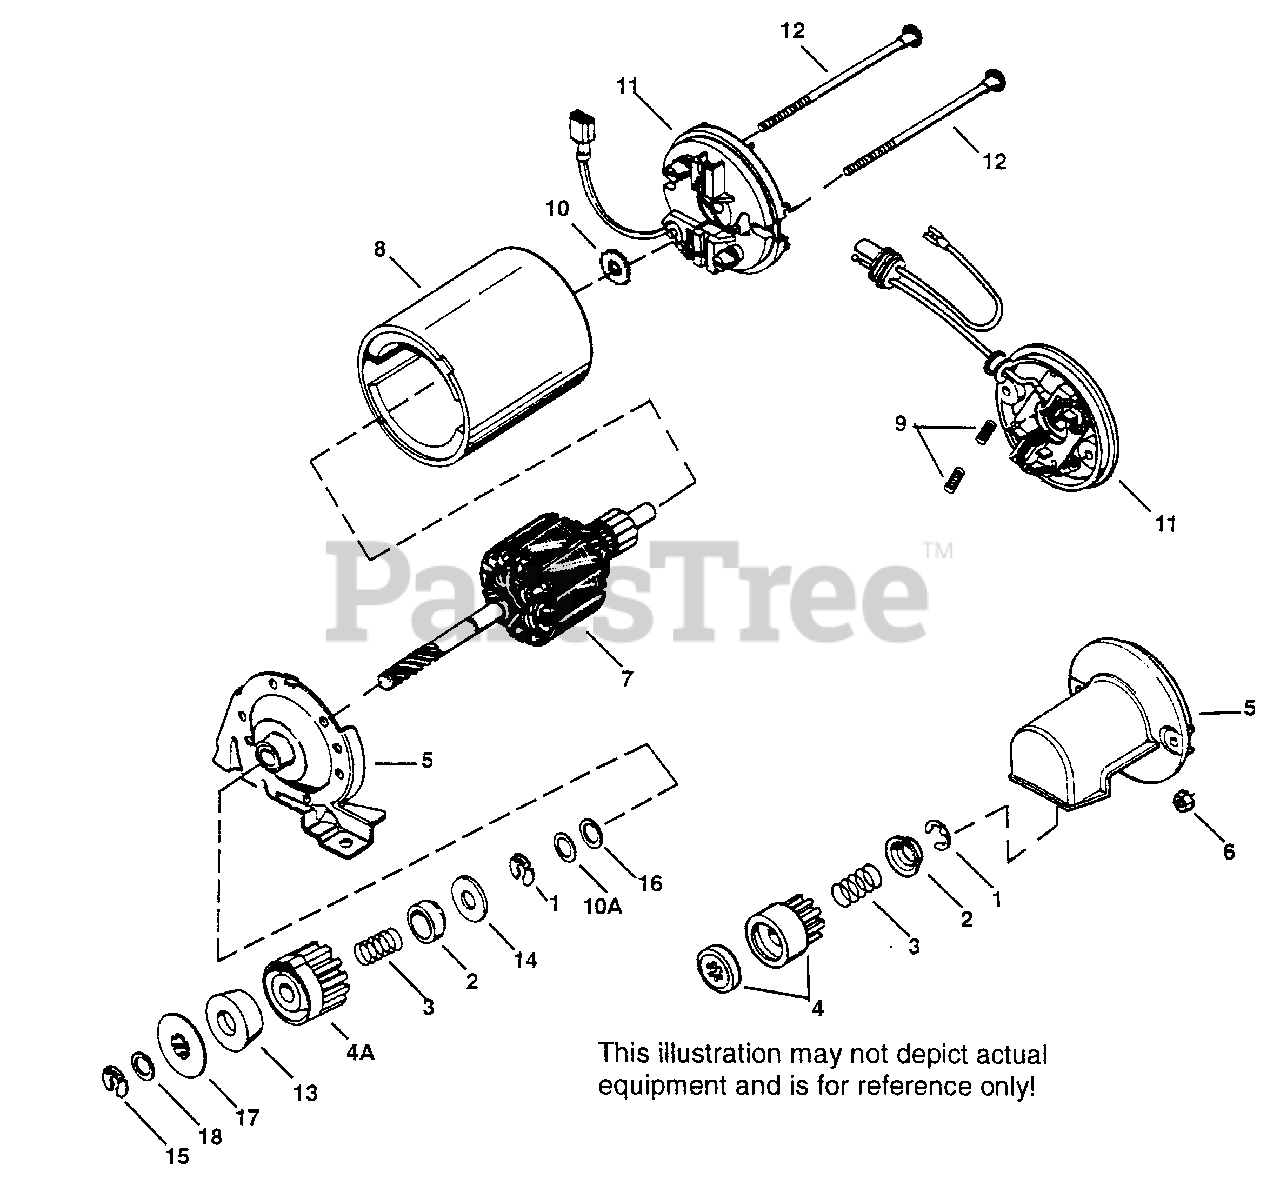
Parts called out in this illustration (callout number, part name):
1	Retainer Ring
2	Spring Retainer
3	Anti-drift Spring
4	Gear
5	Drive End Cap Ass'y.
6	Lock Nut
7	Armature
8	Housing Ass'y.
9	Brush Spring
10	Thrust Washer
11B	Commutator End Cap Ass'y. (Incl. (2)o f 9)
12	Bolt, 10-32 x 3-1/4"
